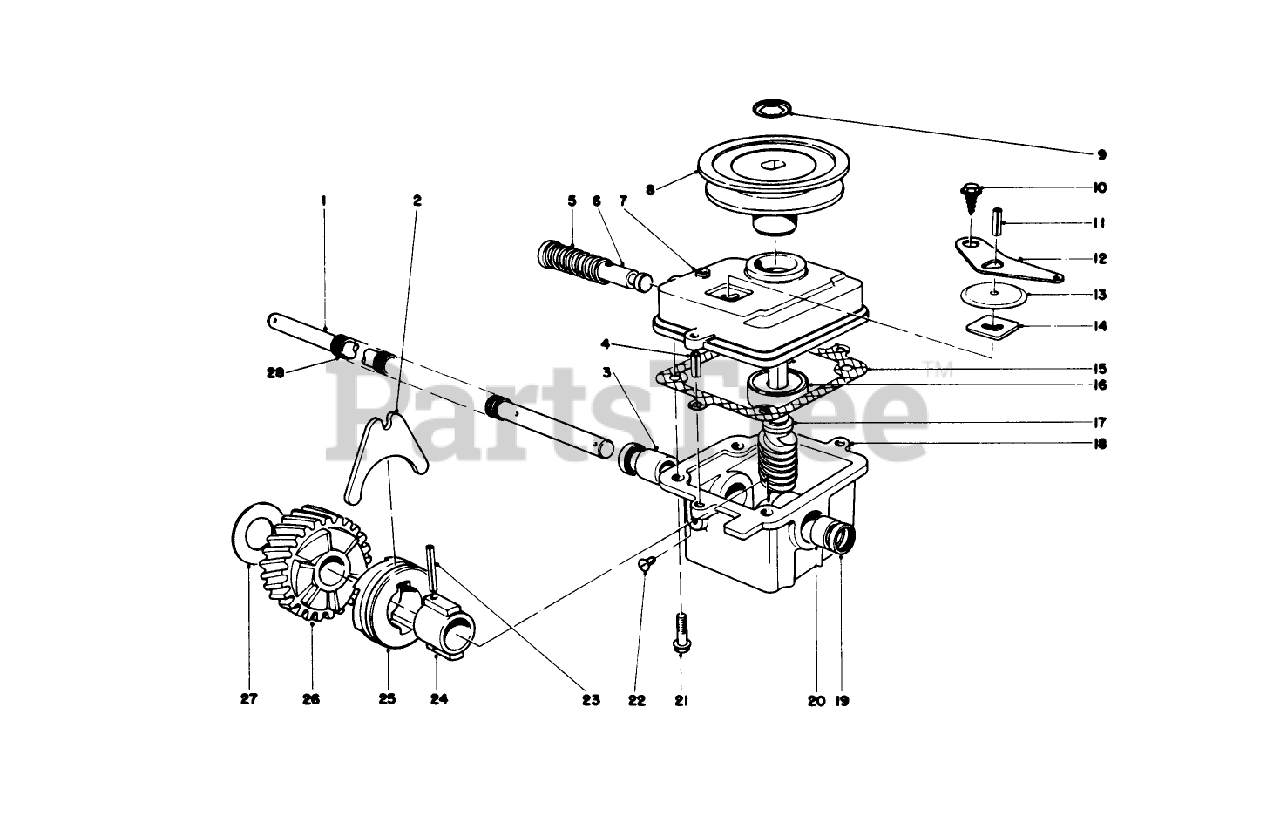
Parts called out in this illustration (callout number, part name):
2	SHIFTER FORK
4	3/16 X 1/2 ROLL PIN
5	SPRING
6	MANUAL-INSTALL
9	216 Washer
11	PIN-ROLL
12	SHIFTER ARM
13	TRANS DUST COVER
14	LATCH PLATE
15	GASKET
18	GEAR CASE ASM
20	Bushing
22	NYLON SCREW
23	COIL PIN
24	SLEEVE
25	CLUTCH JAW
26	Helical Gear
27	THRUST WASHER
